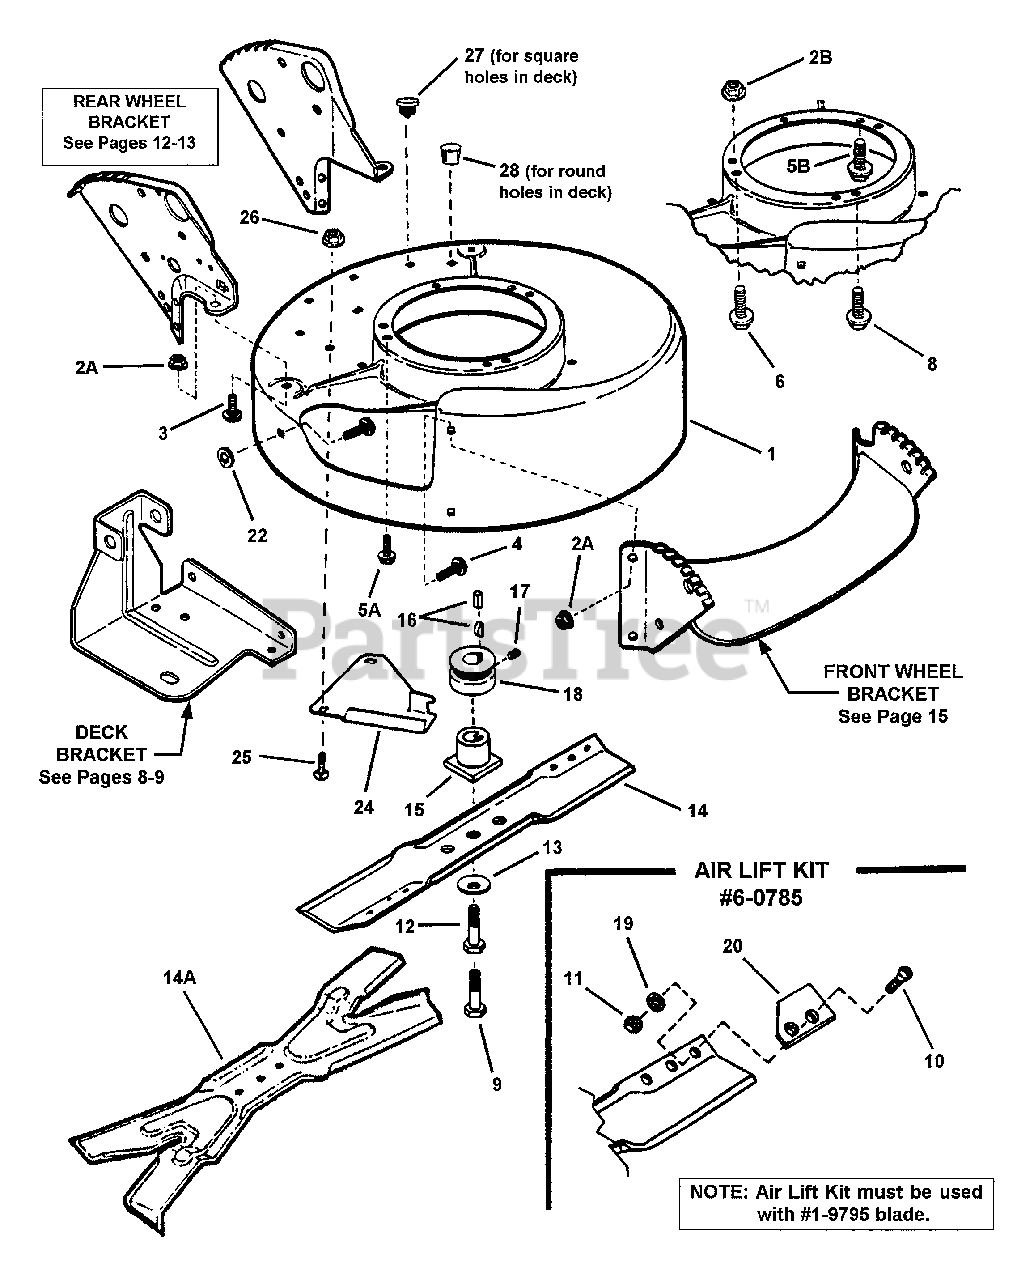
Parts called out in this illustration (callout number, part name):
1	DECK, Mower
2A	NUT, 5/16-18 Hex Flange Lock, Grade 5
2B	NUT, 5/16-18 Hex Flange Lock, Grade 5
3	BOLT, 5/16-18 x 1/2" Short Neck Carriage, Grade 5
4	BOLT, 5/16-18 x 1-1/8" Short Neck Carriage, Grade 5
5A	SCREW, 3/8-18 x 1" S.-Tap (Engine Mount)
5B	SCREW, 3/8-18 x 1" Self-Tap (Engine Mount)
6	BOLT, 5/16-18 x 1-1/2" Hex Flange Lock, Grade 5
8	BOLT, 5/16-18 x 3/4" Hex Flange Lock, Grade 5
9	SCREW, 3/8-24 x 1-3/4" Hex Hd. Cap, Grade 5
10	SCREW, 5/16-24 x 21/32" Machine
11	NUT, 5/16-24 Hex, Grade 5
12	SCREW, 3/8-24 x 2" Hex Head Cap, Gr. 5
13	WASHER, Cone
14	BLADE, Cutter (20.75")
14A	BLADE, Cutter (20.75") (Quad Edge)
15	HUB, Blade Drive 25mm
16	KEY, #505 Hi Pro
17	SCREW, 5/16-18 x 5/16" Hex Socket Set
18	PULLEY, Engine
19	WASHER, 5/16 Internal Tooth Lock
20	LIFT, Air
22	RETAINER, 5/16 Bolt
24	BAFFLE, Belt
25	BOLT, 5/16-18 x 1/2" Neck Carriage, Grade 5
26	NUT, 5/16-18 Hex Flange Lock, Grade 5
27	PLUG, 5/16" Square Hole
28	PLUG, 5/16" Hole
60785	KIT, Air Lift
